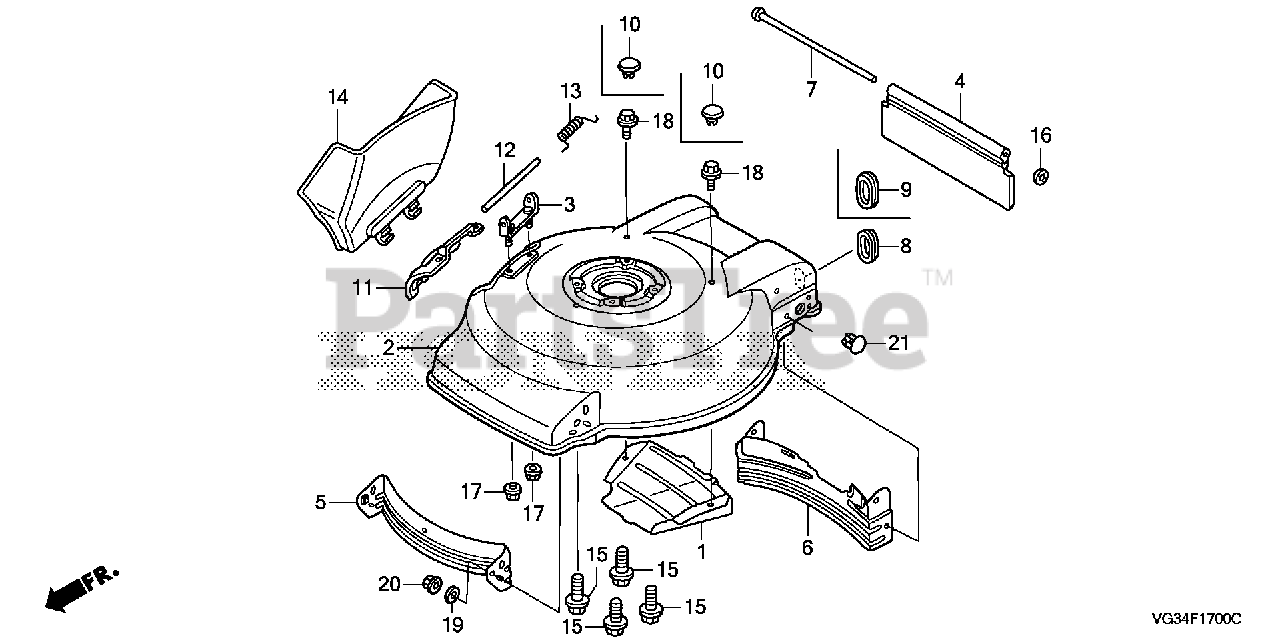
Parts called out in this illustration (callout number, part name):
2	HOUSING, CUTTER *NH190M* (VINTAGE GRAY METALLIC)
3	HINGE, DISCHARGE GUARD
4	SHIELD, RR. (N/A: USE 06761-VG3-305 WHICH INCL. SHIELD, SHAFT, PUSH NUT)
5	SCROLL, FR.
6	SCROLL, RR.
7	SHAFT, RR. SHIELD (403MM)
7	SHAFT, RR. SHIELD (405MM)
9	GROMMET, PLUG
10	PLUG, HOLE
11	GUARD, DISCHARGE *NH105* (MAT BLACK)
12	SHAFT, DISCHARGE GUARD
13	SPRING, GUARD RETURN
14	CHUTE, SIDE DISCHARGE *NH105* (MAT BLACK)
15	BOLT, FLANGE (5/16-24X1")
16	NUT, PUSH (3.96MM) (FLAT ROUND TYPE)
17	NUT, FLANGE (6MM)
19	WASHER, PLAIN (5/16)
20	NUT, FLANGE (8MM)
